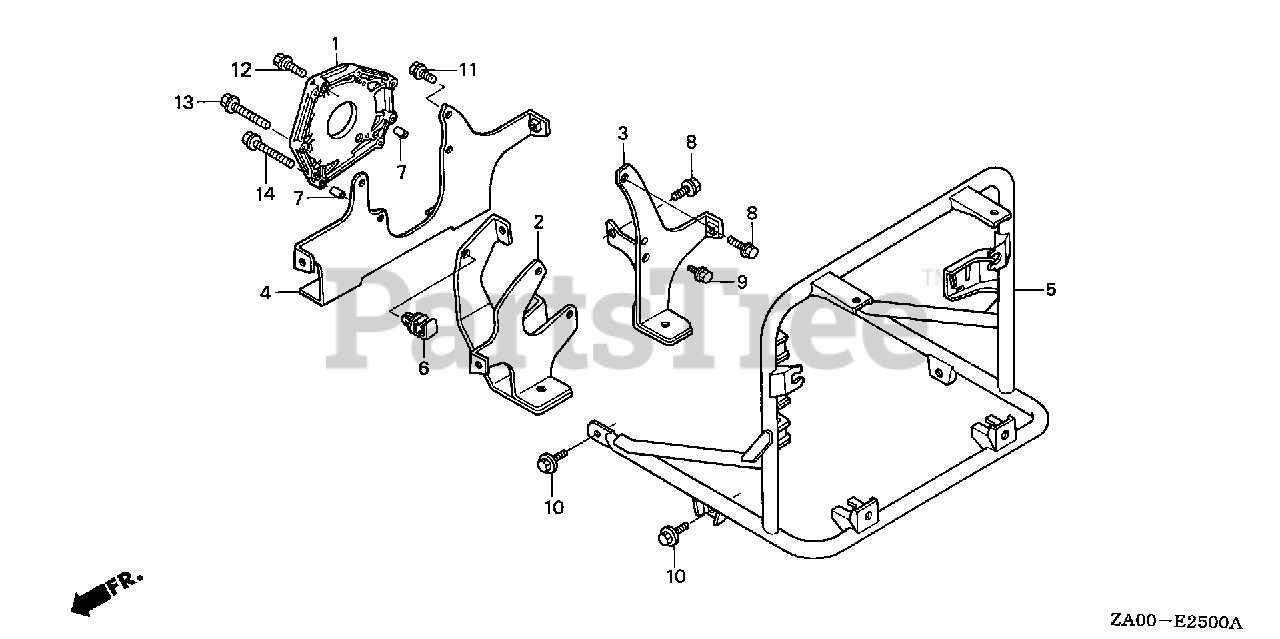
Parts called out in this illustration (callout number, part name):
2	STAY, R. FR. ENGINE MOUNTING
3	STAY, L. FR. ENGINE MOUNTING
4	STAY, R. RR. ENGINE MOUNTING
5	FRAME
6	CLIP, WIRE HARNESS
8	BOLT, FLANGE (8X20) Use up to Engine SN 1609606.
9	BOLT, FLANGE (6X10)
10	BOLT, FLANGE (8X16) Use from Engine SN 1000016.
11	BOLT, FLANGE (8X20) Use up to Engine SN 1609606.
12	BOLT, FLANGE (8X25)
